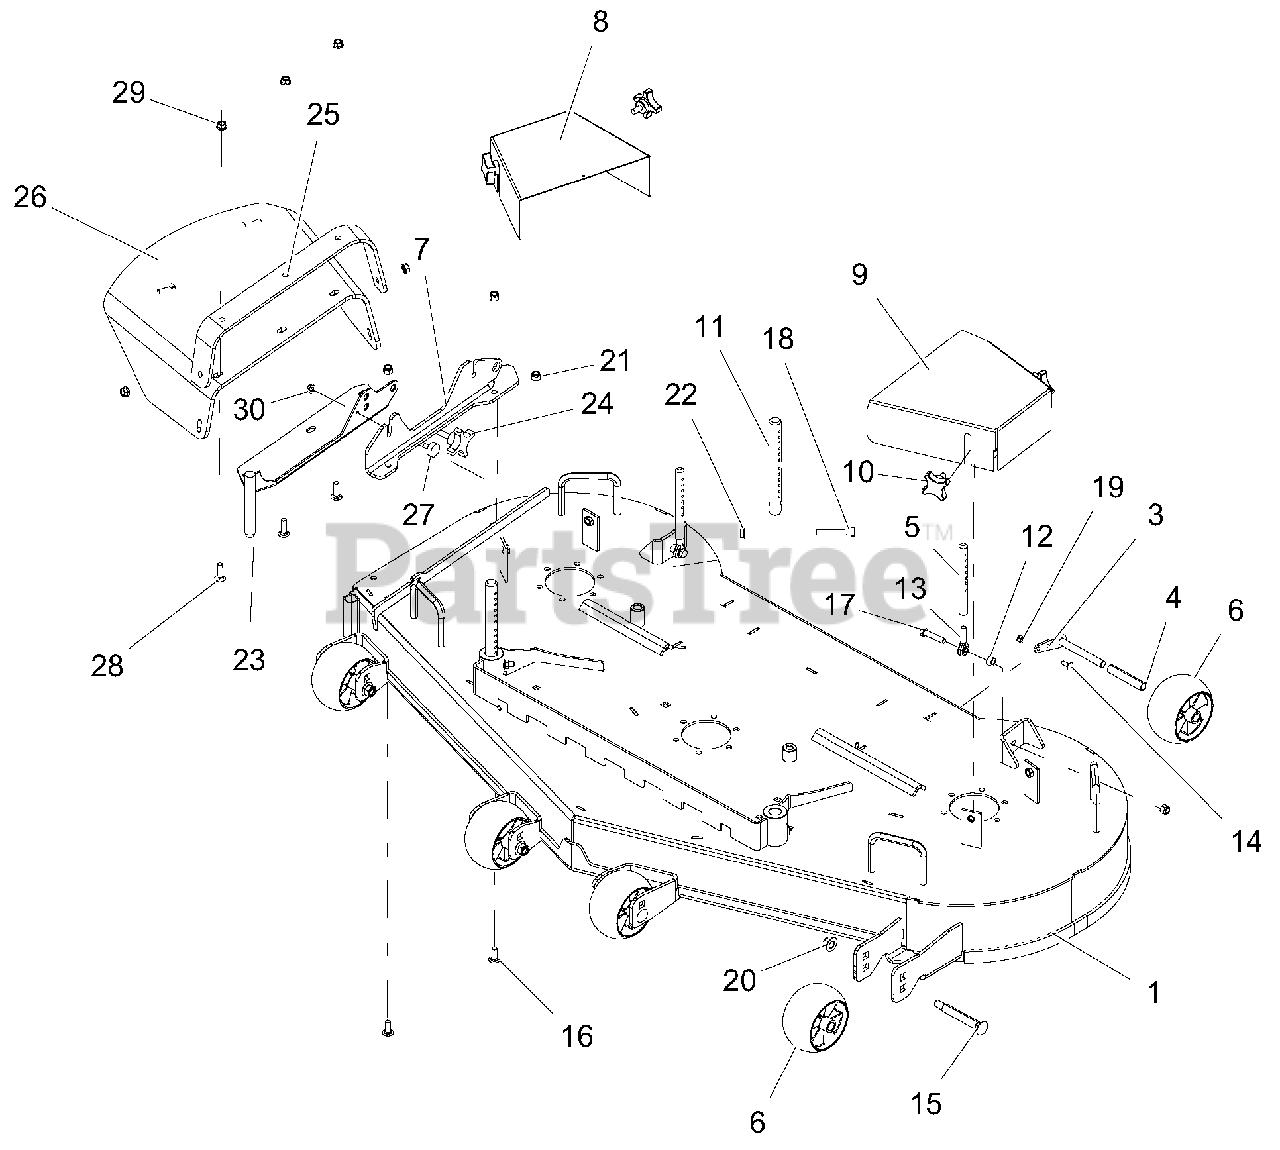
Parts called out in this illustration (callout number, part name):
1	DECK, WITH DECALS 61"
3	PIVOT, RETAINING WELD
4	SPACER, .510X.625X3.35
5	ROD, REAR HOC
6	ANTI-SCALP WHEEL - 5X3 CTR
7	DISCHARGE, RUBBER BRKT
8	PULLEY, SHIELD-RED
9	PULLEY, SHIELD LH-RED
10	KNOB, 3/8-16 x .75
11	PIN, FRONT HOC 61
12	BSHG, SLV REV
13	ROD, END 3/8 RH
14	@BLT-RDHDSQNK .25-20X.75 G5 YWZC
15	@BLT-RDHDSQNK .50-13X4.50 G5 YWZC
16	@BLT-RDHDSHSQNK.38-16X1.0 G5YZ
17	BLT-HEX .38-16X1.75 GR5 YWZC
18	BLT-HEX .38-16X2.50 GR5 YWZC
19	@NUT-LK-NYL .250-20 YWZC
20	NUT-LK-NYL-FLG .50-13 YWZC
21	@NUT-LK-NYL .38-16 YWZC
22	@NUT-SPNLK-FLG .375-16 YWZC
23	WLDT. DISCHARGE-RED
24	KNOB, 3/8 X 1.25 - 4 PRONG
25	STRAP, WALK RUBBER DISCHARGE-RED
26	SHIELD, WALK RUBBER DISCHARGE
27	BUMPER, RUBBER
28	@BLT-RDHDSQNK .38-16X1.25 G5 YWZC
29	@NUT-SPNLK-FLG .375-16 YWZC
30	@NUT-SPNLK-FLG .312-18 YWZC
